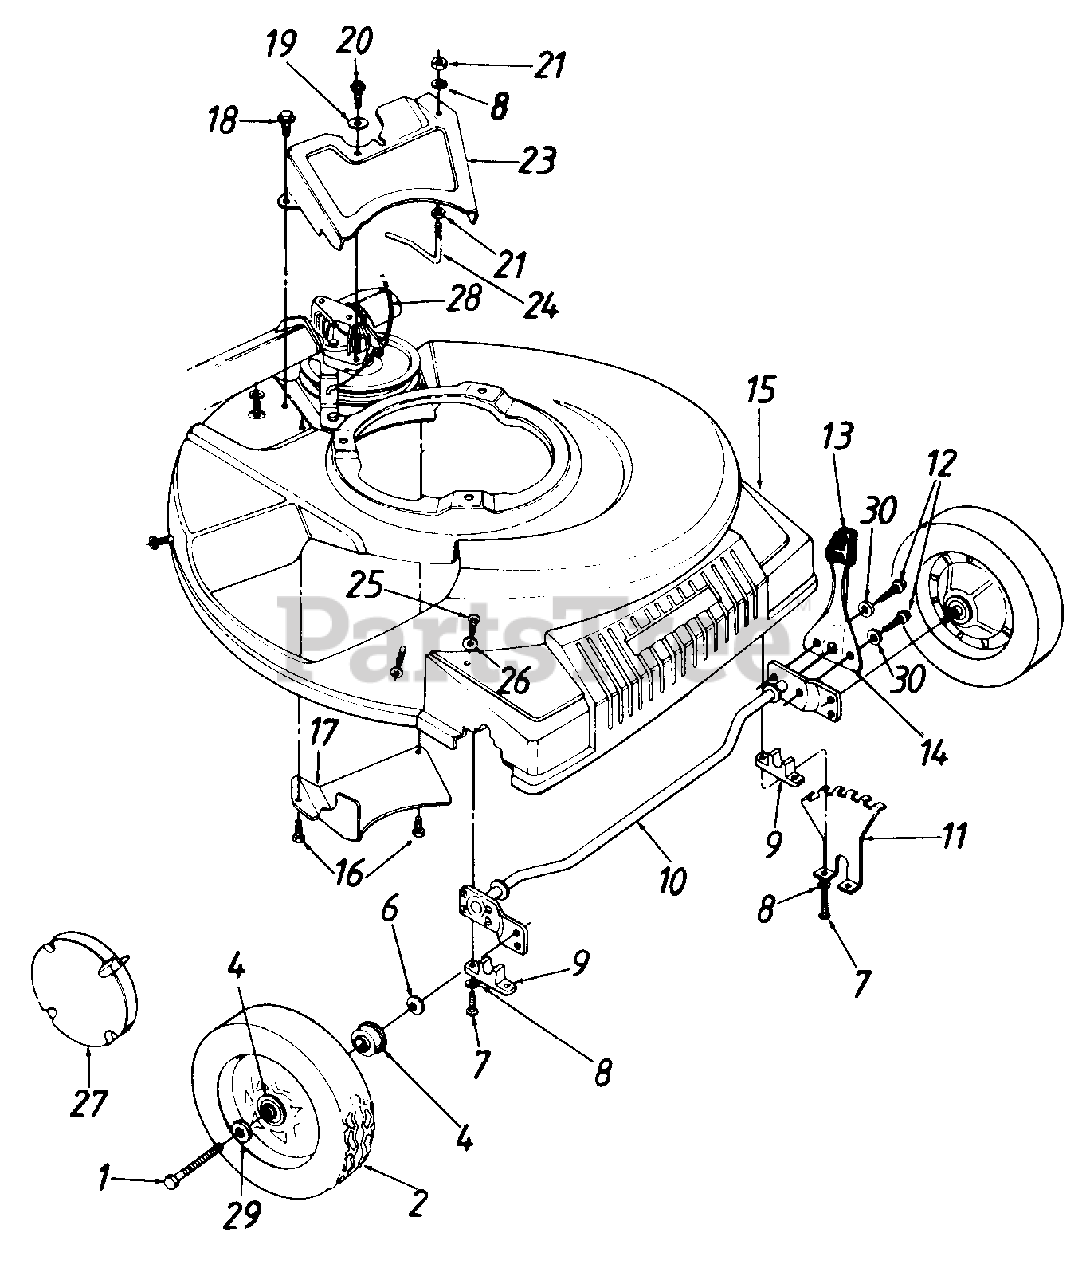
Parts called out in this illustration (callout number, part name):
1	Front Axle Bolt
2	Wheel Ass'y. Comp. 8 x 2"
4	Flange Ball Brg. .501" I.D.
6	Bell-Wash. .380" I.D. x .88
7	Hex Wash. Hd. B-Tap Scr. 1/4-20
8	L-Wash. 1/4" I.D.
9	Block Bushing
12	Hex Wash. Hd. TT-Tap Scr. 1/4-20 x .38" Lg.
13	Knob
14	Spring Lever
15	Plastic Front End
16	Hex B-Tap Scr. 1/4" x .38"
19	Bell-Wash. .265" I.D. x .75
20	Hex Wash. Hd. B-Tap Scr. 1/4 x .62
21	Hex Nut 1/4-20 Thd.
25	Truss B-Tap Scr. 5/16 x 75"
26	Bell-Wash. .345 I.D. x .88" O.D.
27	Hub Cap
28	S.P. Cable 60" Lg.
29	Wave Wash. .53 I.D. x 78" O.D.
30	External L-Wash. 1/4" I.D.
